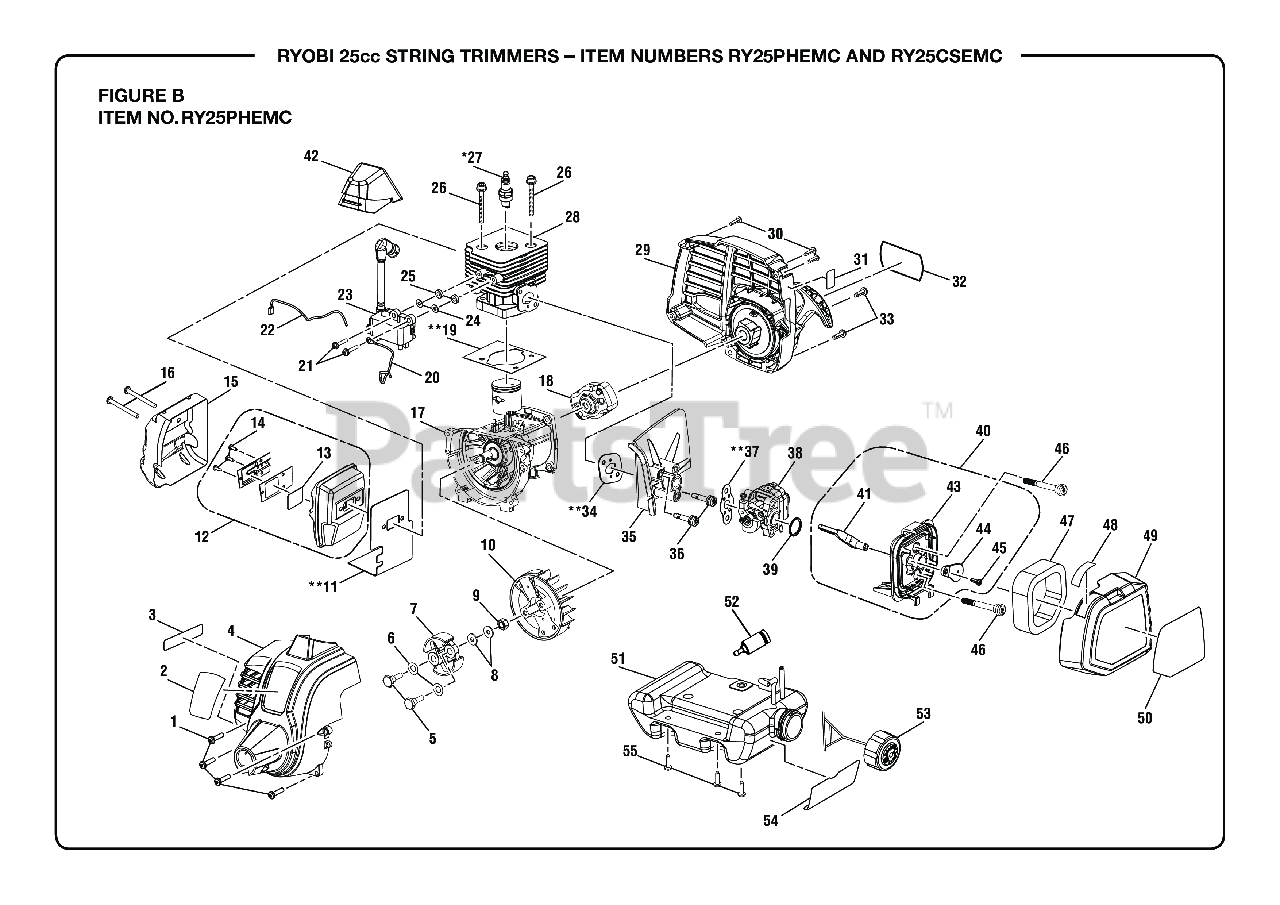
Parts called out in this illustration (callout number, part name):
1	Cap Screw w/Washer (M5 x 16 mm, T25 Torx Soc. Hd.)
2	Logo Label (Front)
3	Warning Label (Combustion)
4	Front Housing Assembly w/ Labels
5	Clutch Shoulder Bolt (M6 x 22.5 mm, Hex Hd.)
6	Washer (Curved)
7	Clutch Assembly
8	Washer (ID6 x OD15 x 1.2t)
9	Flange Nut (M8, Flywheel)
11	Muffler Gasket
12	Muffler Assembly
13	SCREEN
14	Screw (6-20 x 1/4 in., T20 Torx Pan Hd. S.T.)
15	HEAT SHIELD
16	Screw (M5 x 50 mm, Torx Slotted Recessed Pan Hd.)
17	Crankcase Assembly
18	Starter Cup
19	Gasket
20	Lead Wire Assembly, Red
21	Screw (M4 x 22 mm, T20 Torx Slotted Recessed Pan Hd.)
22	Lead Wire Assembly, Black
23	Coil Boot Assembly
24	Flat Washer (OD10 x ID42 x 1t)
25	Phenolic Spacer (Ignition Module)
26	Screw (M5 x 22 mm, T25 Torx Soc. Hd.)
27	SPARK PLUG CHAMPION - RCJ-6Y
29	Rear Housing and Starter Assembly
30	Screw (M4 x 20 mm, T20 Torx Pan Hd. S.T.)
31	Primer Bulb Location Label
32	Shoulder Screw (M4 x 14 mm, T25 Torx Truss Hd.
33	Cap Screw w/Washers (M5 x 16 mm, T25 Torx Soc. Hd.)
34	Heat Dam Insulator
35	Screw (M5 x 30 mm, T25 Torx Pan Hd. S.T.)
36	Screw w/Washers (M5 x 30 mm, T25 Torx Pan Hd.)
37	Gasket
38	Carburetor Assembly
39	Carburetor O-Ring
40	Airbox Base Assembly
41	Compression Limiters
42	Spark Plug Boot
43	Air Box Base
44	Screw (M4 x 12 mm, T20 Torx Pan Hd. S.T.)
45	Screw (M4 x 12 mm, Slotted Recessed Pan Hd.)
46	Screw (M5 x 45 mm, T20 Torx Truss Hd.)
47	Air Filter (Element)
48	Choke Position Label
49	Airbox Cover (Inc. Key Nos. 48 & 50)
50	Starting Instructions Label
51	Fuel Tank and Cap Assembly
52	Fuel Filter
53	Fuel Cap Assembly
54	Fuel Mixture Label
55	Shoulder Screw w/Washer (M4 x 14 mm, T25 Torx Truss Hd.)
